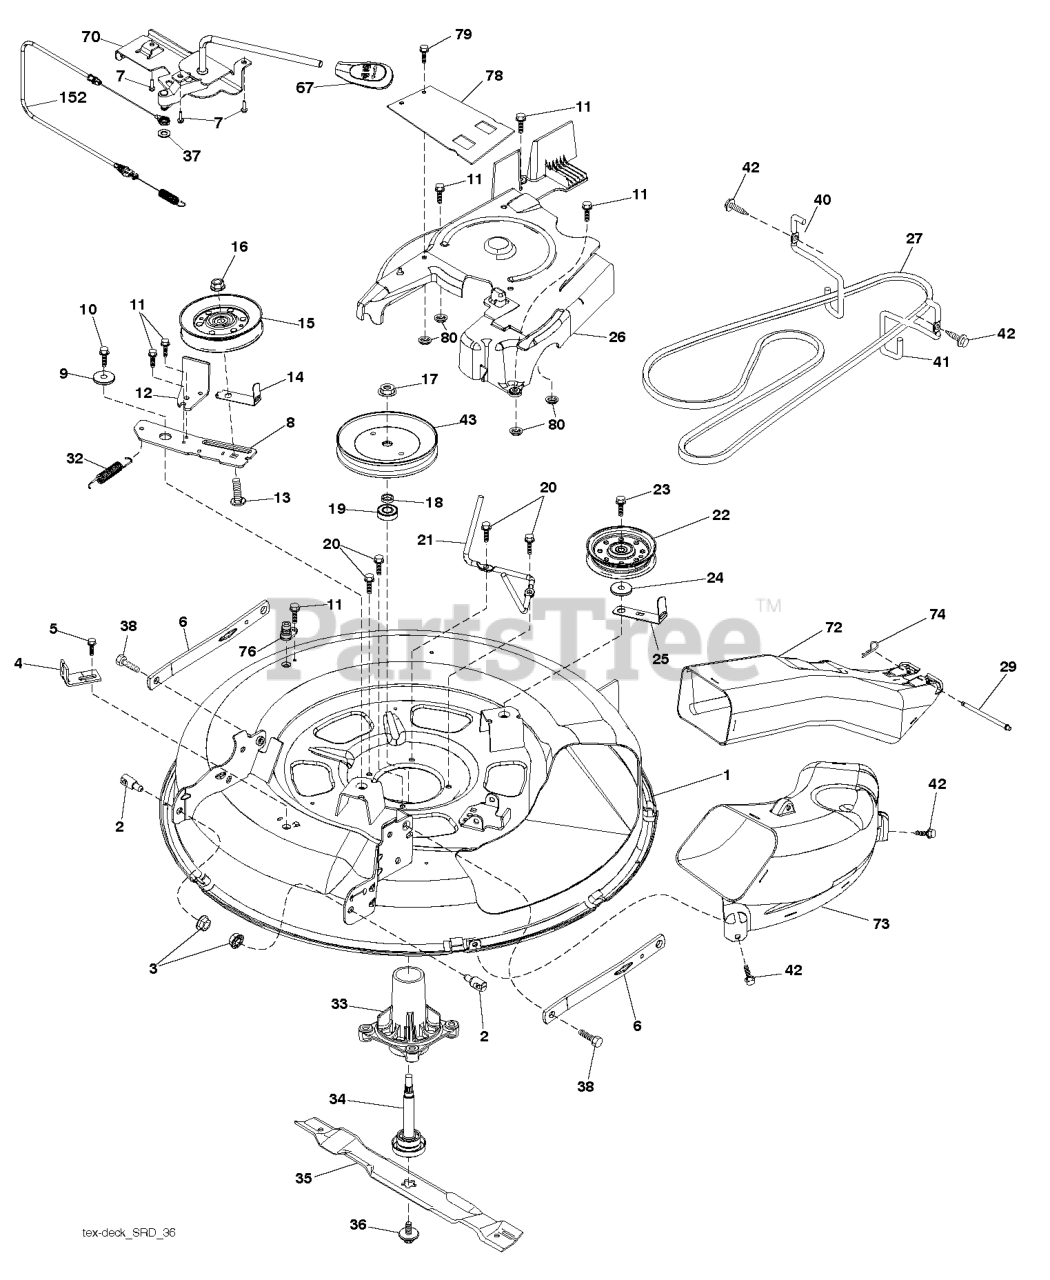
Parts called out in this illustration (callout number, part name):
1	DECK.WELDMENT.PNT.30"SRD
2	STUD.FASTNER.W/ANTI-ROTATE
3	NUT LOCK HEX FLANGE 5/16-18
4	BRACKET.CLUTCH.CABLE
5	BOLT.5/16HEX.WHS.HD
6	ARMS.SUSP.MOWER.REAR.SRD
7	SCREW.#10 X 0.750.BOS
8	ARM.IDLER.30"SRD
9	SPACER.RETAINER
10	SCREW 3/8-16X1
11	SCREW.1/4-20X5/8
12	RP ARM.BRAKE.MOWER.38"LH.TEX
13	BOLT.3/8-16X1.50
14	KEEPER, BELT IDLER
15	PULLEY.IDLER.4.25
16	NUT LOCK FLG 3/8-16 UNC
17	NUT.FLANGE.LOCK.TOP
18	WASHER.SPACER.MANDREL
20	SCREW, WASHER HEAD
21	KEEPER.BELT.MANDREL.30"
22	PULLEY.IDLER.FLAT.46.PR.DR.
23	SCREW LT
24	WASHER
25	KEEPER.BELT.30"SRD
26	COVER.ASM.MANDREL.30"
27	V-BELT.DRIVE.MOWER.30"
29	PIN.HINGE.30".SRD
32	SPRING RETURN
33	RP.HOUSING.MANDREL.4PT.
34	SHAFT.ASM.MDRL.N/GREASE.38
35	BLADE.MOWER.BAGGING.30"
36	BOLT.WASHER.ASM.7/16-2
37	WASHER
38	BOLT.SHOULDER
40	KEEPER.BELT.ENGINE.LH.LT.SRD
41	KEEPER.BELT.ENGINE.RH.LT.SRD
42	SCREW, 3/8-16X3/4
43	PULLEY, MANDREL 6.5 PD
67	HANDLE.CLUTCH.CABLE.LT
70	CLUTCH.ASM.MANUAL.LT.PRED
72	CHUTE.UPPER.SRD.30R"
73	CHUTE.LOWER.SRD.30R"
74	RETAINER-SPRNG RB
76	PORT.WASHOUT
78	GUARD ARM CLUTCH
79	SCREW.HI-LO.CONSOLE
80	PALNUT 1/4
152	CABLE.CLUTCH.MANUAL.
